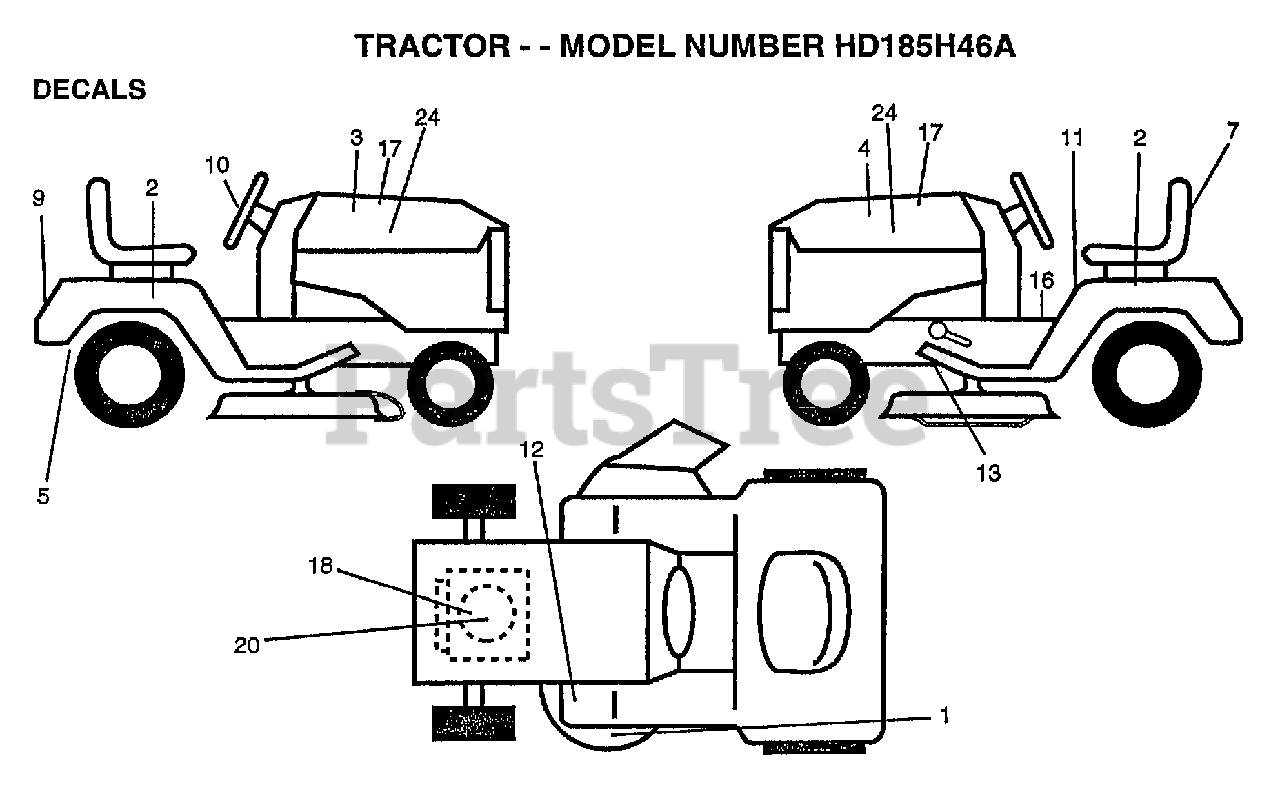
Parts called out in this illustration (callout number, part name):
1	"DECAL DECK,MULCH"
2	DECAL FENDER SIDE
3	"DECAL-HOOD,RH"
4	DECAL HOOD LH
5	DECAL DRAWBAR LH
7	DECAL SEAT REPLCM
9	"DECAL FENDER,LOGO"
10	"DECAL WHEEL,STEER"
11	"DECAL FENDER,DANG"
12	DECAL CLUT/BRAKE
13	"DECAL.V.BELT.44"""
18	DECAL, HP ENGINE
20	DECAL ENG REPLCMT
